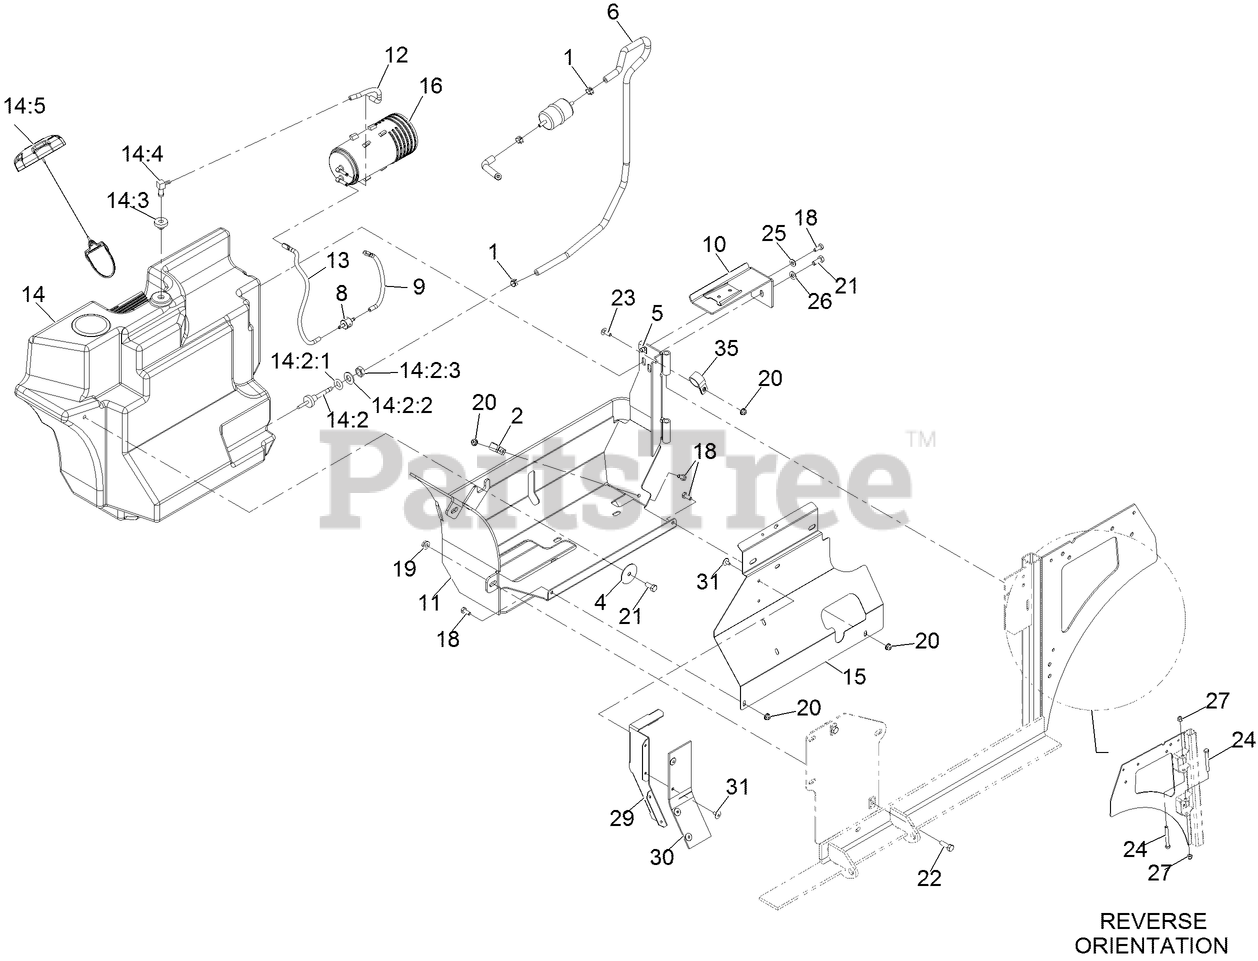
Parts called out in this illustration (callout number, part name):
1	CLAMP-HOSE
2	CLIP-LOOM
6	HOSE-FUEL
8	VALVE-CHECK, VACUUM
9	HOSE-VENT, FORMED
10	CANISTER BRACKET ASM
11	TANK FRAME ASM
12	HOSE-VENT, FORMED
13	HOSE-VENT, FORMED
14	FUEL TANK ASM
14:2	FITTING-FUEL, BULKHEAD
14:2:1	O-RING,BULKHEAD FITTING
14:2:2	WASHER-FLAT
14:2:3	NUT-JAM
14:3	BUSHING
14:5	CAP-FUEL, RATCHETING
15	PANEL-TANK SHIELD
16	CANISTER-CARBON, 800CC
18	SCREW-HH
21	SCREW-HH
22	SCREW-HH
23	BOLT-CARR
24	SCREW-HH
25	WASHER-FLAT
26	WASHER-PLAIN
27	NUT-LOCK, NI
29	DEFLECTOR-AIR
30	FLAP-RUBBER
31	RIVET-POP
35	R-CLAMP
